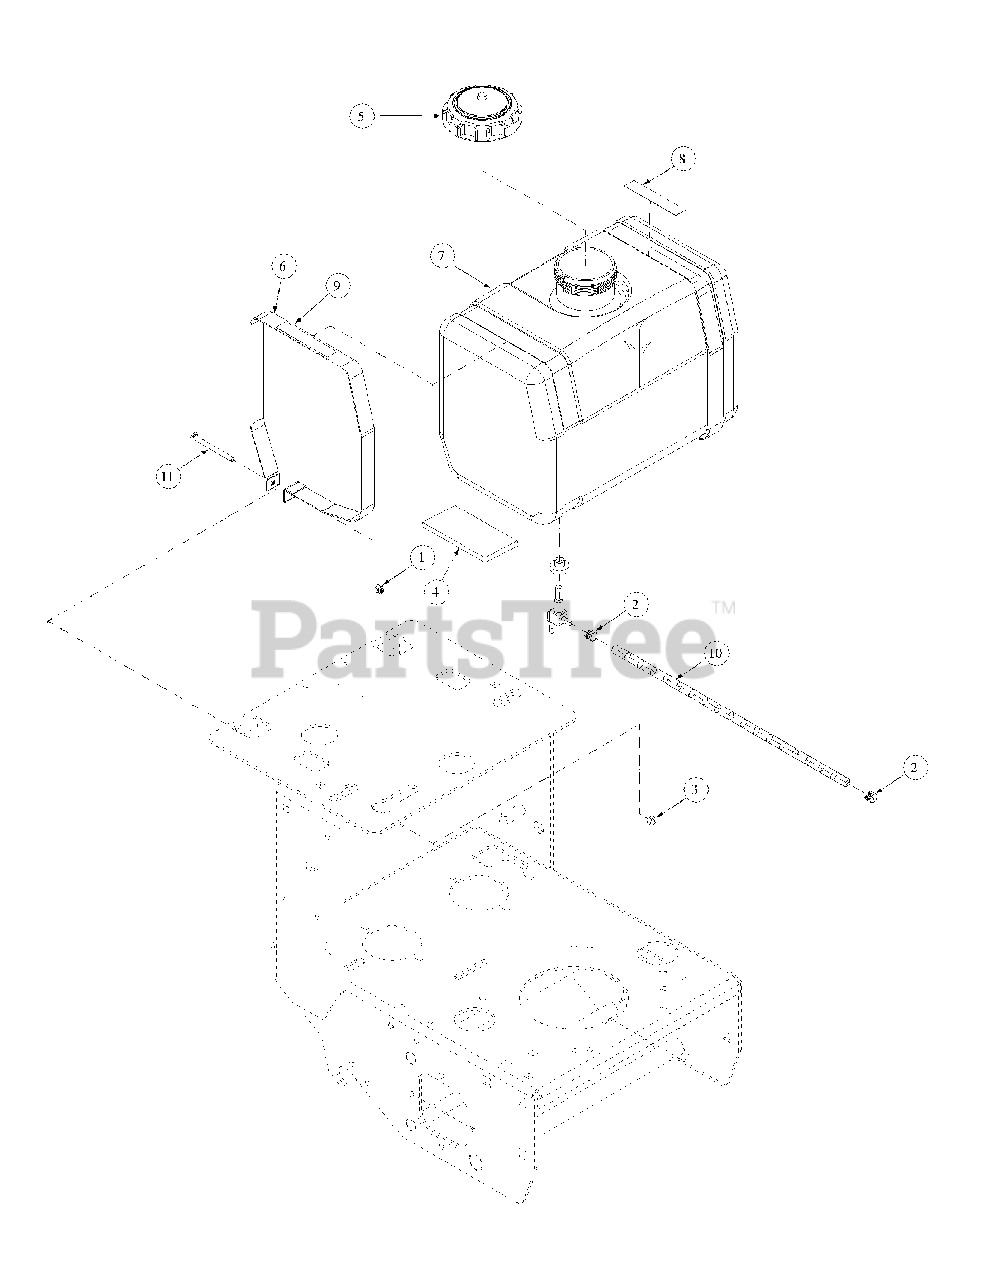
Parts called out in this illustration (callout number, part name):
1	Lock Nut, Nylon Insert, 1/4-20 Grade A
2	Uni-Clamp, #5077-136
3	Nut, 1/4-20, Grade A
4	Stop Pad, Rubber
5	Fuel Cap, 3.5
6	Fuel Tank Strap
7	Fuel Tank
8	Mower Warning Label, Turn Off Engine
9	Mower Instruction Label, Fuel Valve
10	18" Fuel Hose
11	Carriage Bolt, 1/4-20 x 3.00 Grade 5
12	Grommet Fuel Tank
13	Shut Off Fuel Tank
